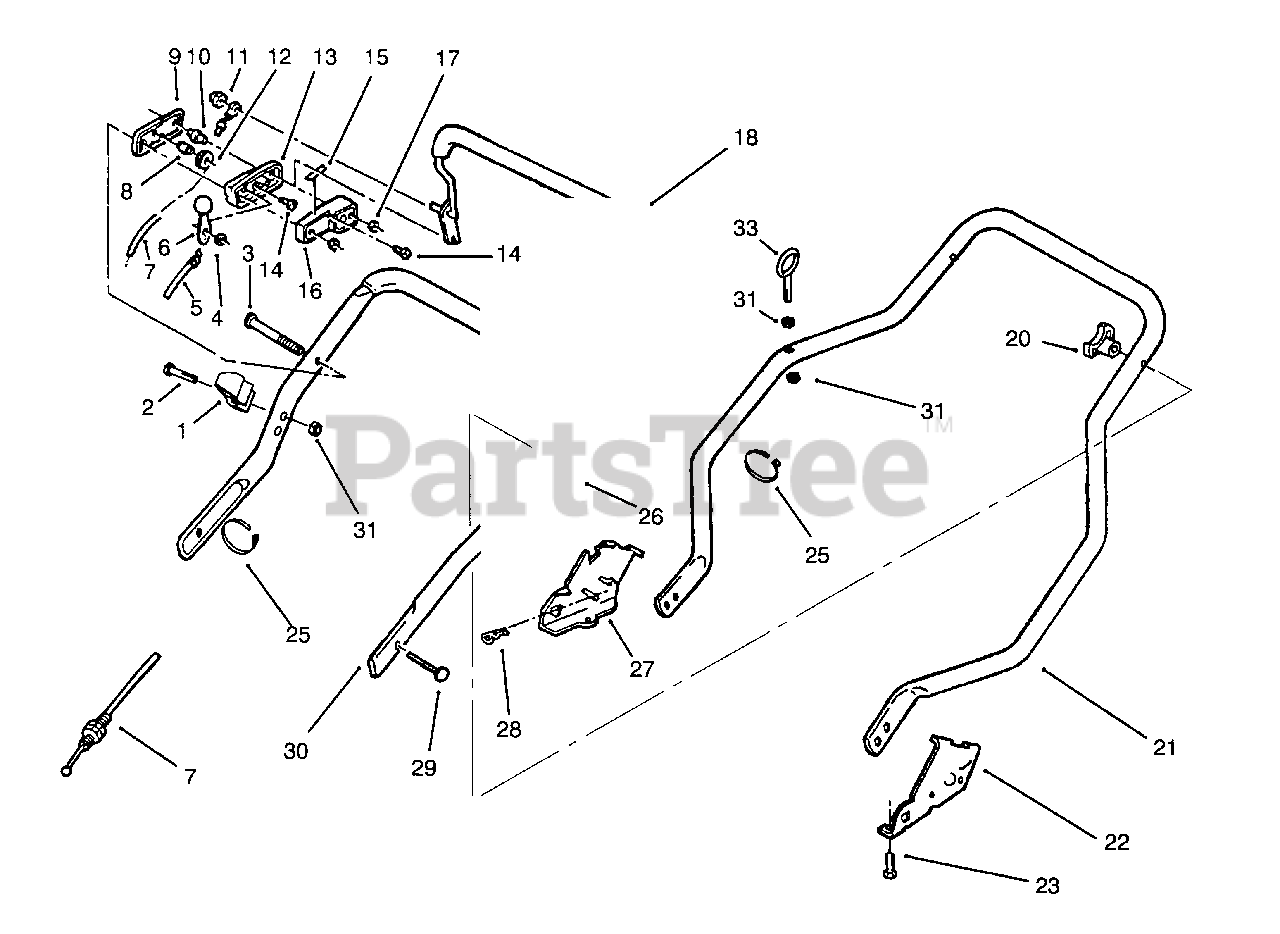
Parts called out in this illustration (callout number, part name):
1	Guide-Rope
5	Cable-Throttle
6	Lever & Knob Assembly
7	Cable-Control
9	Control Case Outer
11	Nut-Acorn
13	Case-Throttle, Center
15	Decal-Throttle
16	Case-Throttle, Inner
18	Lever-Control
20	Knob
21	Handle-Lower
22	Bracket-Handle L.H.
25	Tie Strap
26	Nut-Push
27	Bracket-Handle R.H.
28	Pin-Cotter
30	Handle Assembly-Top
31	Nut-Lock
33	EyeBolt
